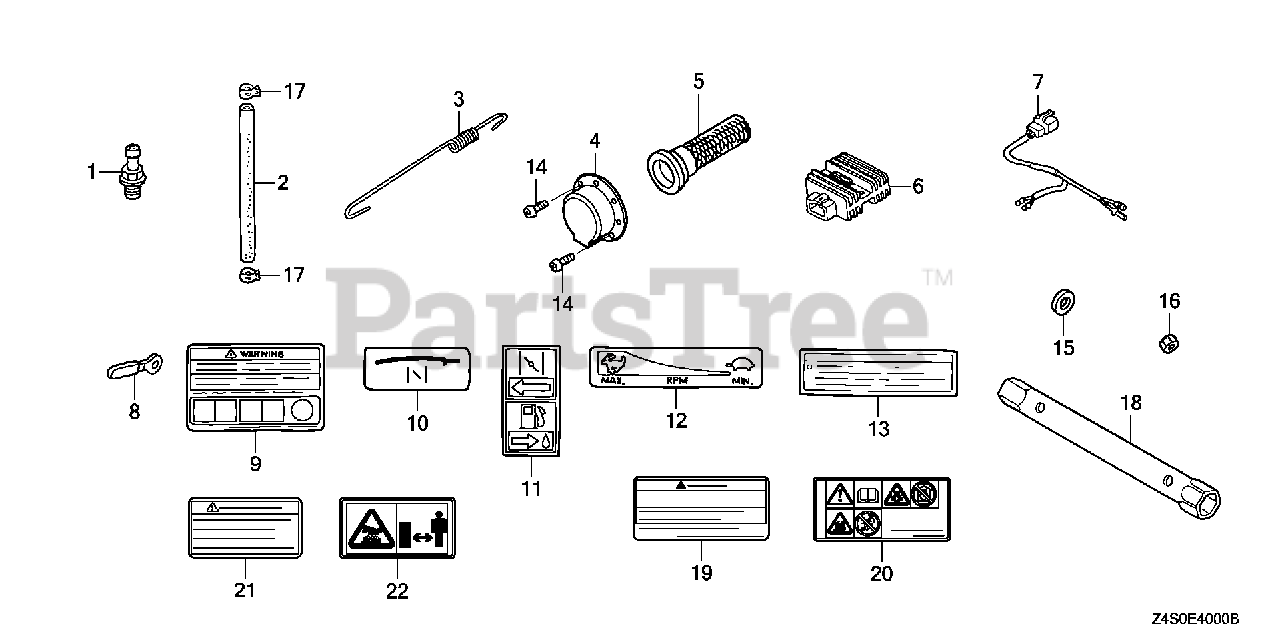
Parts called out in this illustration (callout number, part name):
6	RECTIFIER ASSY., REGULATOR (10A)
7	SUB-WIRE HARNESS ASSY.
9	MARK, OPERATOR CAUTION (FRENCH)(MADE IN JAPAN)
19	MARK, OPERATOR CAUTION (FRENCH)(MADE IN JAPAN)
20	MARK, OPERATOR CAUTION (PICTOGRAPH)
21	MARK, EX. CAUTION (ENGLISH)
21	MARK, EX. CAUTION (FRENCH)
22	MARK, EX. CAUTION (PICTOGRAPH)
